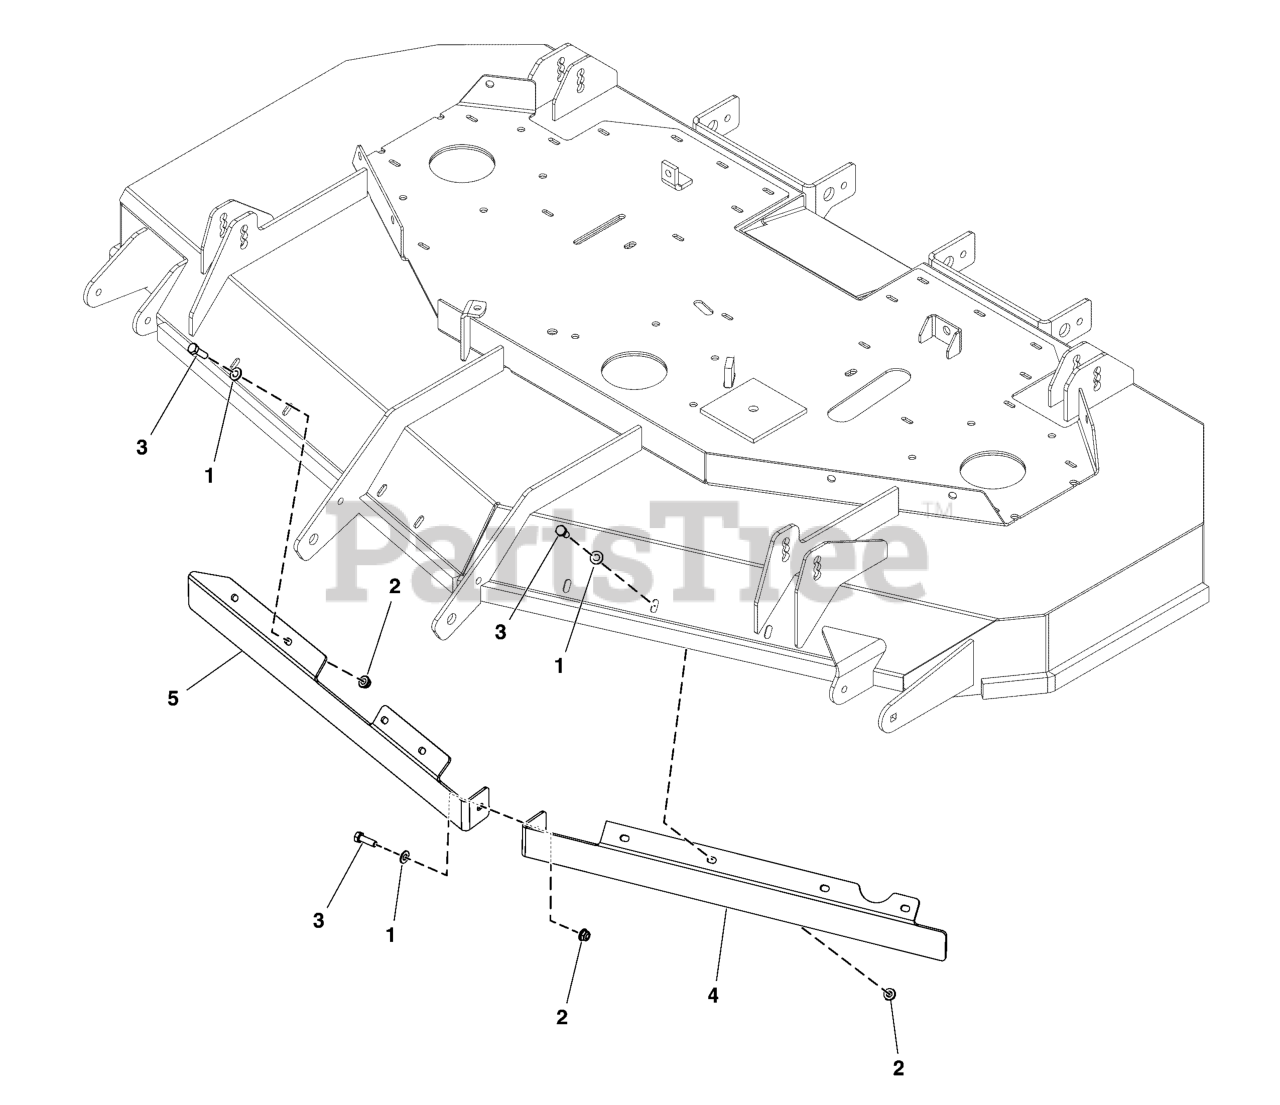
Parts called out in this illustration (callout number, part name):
1	WASHER, 5/16" SAE
2	NUT, 5/16-18 HEX NYLOCK FLANGE NUT
3	BOLT, 5/16-18 X 1" GRD5 YZ
4	BAFFLE, BLOWOUT, 61RD iCD, LH - BLK
5	BAFFLE, BLOWOUT, 61RD iCD, RH - BLK
